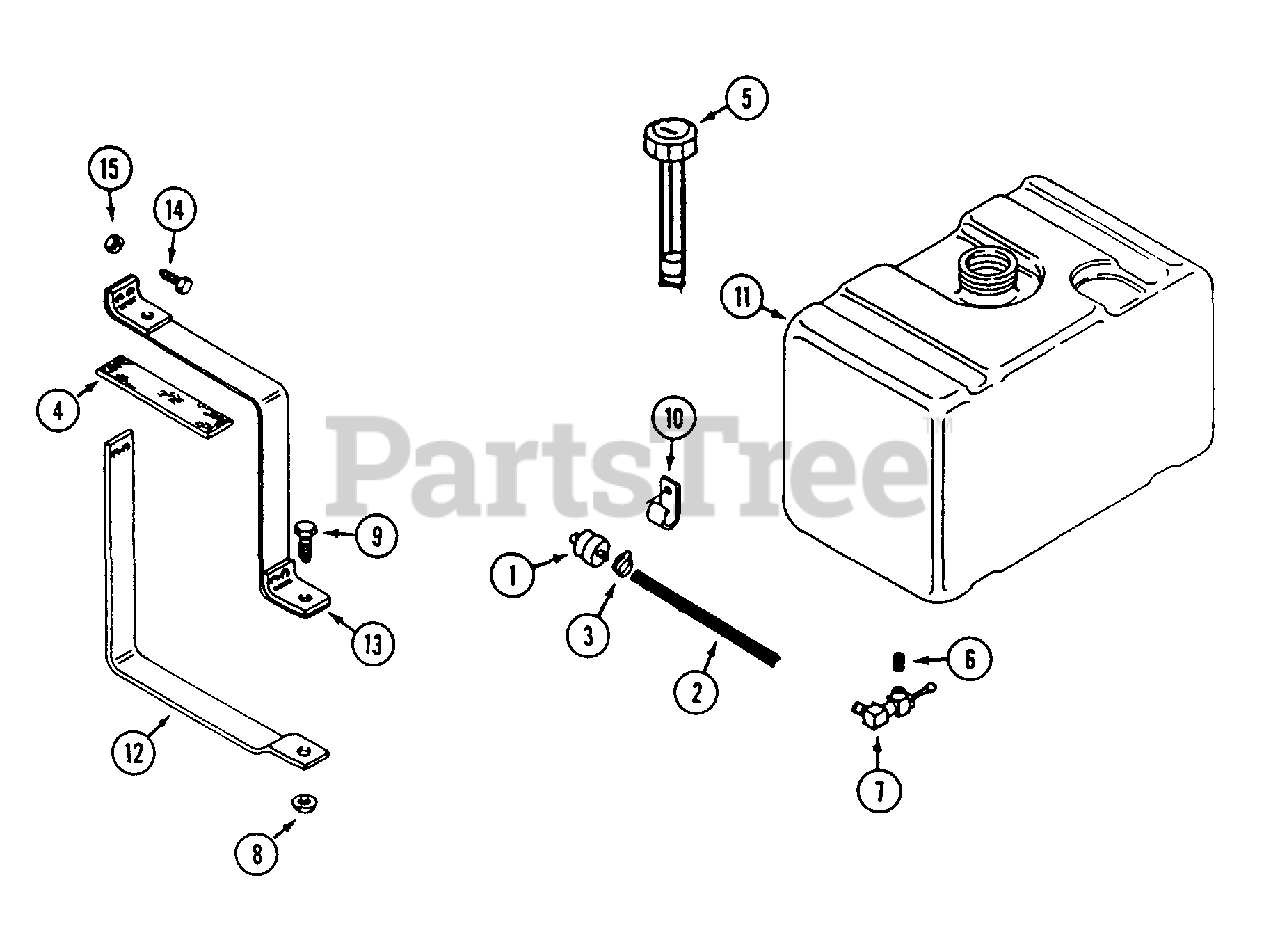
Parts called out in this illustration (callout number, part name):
1	FILTER - fuel
2	HOSE - fuel
5	CAP - fuel tank (with gauge) 2-1/4"
6	NIPPLE - pipe 1/8"
7	VALVE - shut off
8	NUT - 5/16" - 18 flange lock
9	BOLT - 5/16" - 18 x 1"
10	CLIP - "J" fuel line
11	TANK - fuel (2-1/4" filler tube) (plastic)
12	BRACKET - fuel tank
13	STRAP - fuel tank
14	BOLT - 1/4" - 20 x 1-1/2"
15	INPUT - 1/4" - 20 lock
